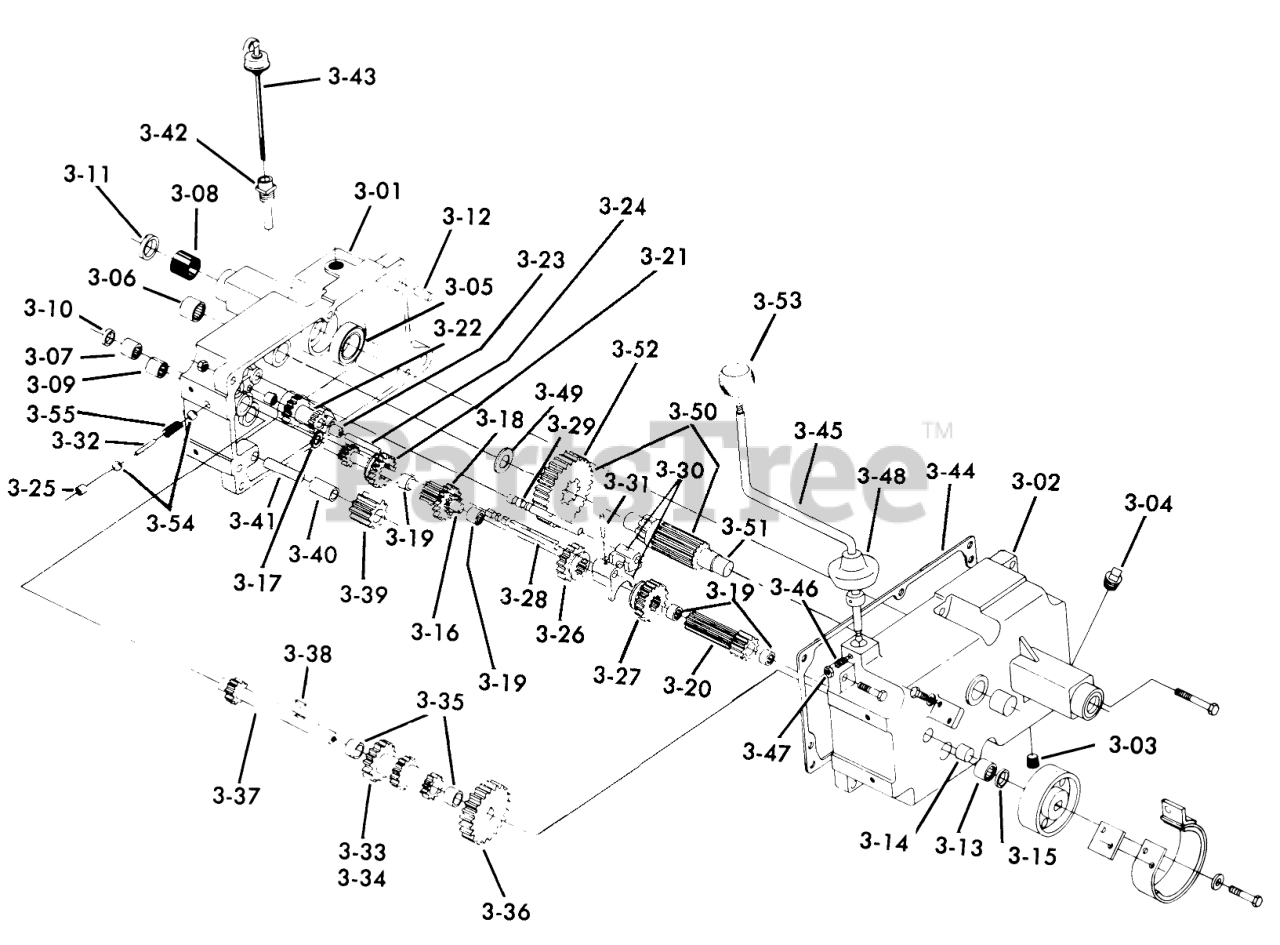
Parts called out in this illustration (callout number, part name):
3-01	Case RH
3-02	Case L.H.
3-02	HHCS
3-02	Bolt
3-02	Nut
3-03	PLUG 1/4 PIPE ALLEN
3-04	Plug
3-05	BALL BRG 1 1/2 I.D.
3-06	BEARING-NEEDLE
3-07	BEARING-NEEDLE
3-08	Bearing 1-1/8" I.D.
3-09	BEARING-NEEDLE
3-10	SEAL-OIL
3-11	SEAL-OIL
3-12	PIN-DOWEL
3-13	BEARING-NEEDLE
3-14	Bearing Needle
3-15	SEAL-OIL
3-16	SHAFT-INPUT
3-17	WASHER-THR
3-18	GEAR
3-19	BEARING-NEEDLE
3-20	GEAR
3-21	GEAR-SLIDING
3-22	Gear
3-23	BEARING-NEEDLE
3-24	GEAR-SHAFT REDUCTION
3-25	CUP-PLUG
3-26	GEAR-HI AND 2ND
3-27	GEAR-LOW AND REVERSE
3-28	RAIL-SHIFT
3-29	RAIL-REAR SHIFT
3-30	FORK-SHIFT
3-31	PIN-ROLL
3-32	PIN-SHIFT
3-33	GEAR-CLUSTER
3-34	Cluster Gear
3-35	BUSHING-BRONZE
3-36	GEAR-CLUSTER SHAFT
3-37	Cluster Shaft
3-38	Key
3-39	GEAR/BUSHING ASM-REVERSE IDLER
3-40	BUSHING
3-41	PIN-DIFFERENTIAL
3-42	NIPPLE-FILL, TRANSMISSION
3-43	Dipstick
3-44	GASKET-TRANSMISSION
3-45	Shift Stick
3-46	SETSCREW
3-47	Nut
3-48	COVER-DUST
3-49	WASHER-THRUST
3-50	GEAR ASM
3-51	PINION SHAFT
3-53	SHIFT KNOB
3-54	BALL-DETENT
3-55	Spring
